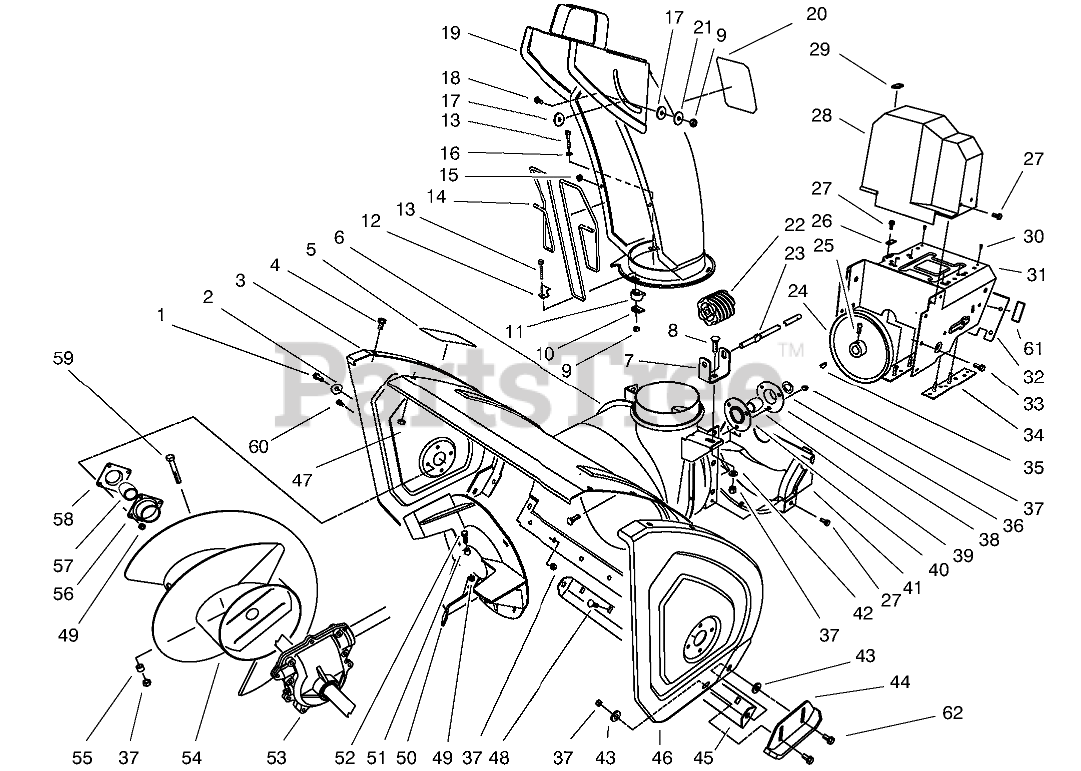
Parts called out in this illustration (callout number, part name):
1	SCREW-HH
2	WASHER
3	Plate-Side
4	SCREW-HHF
5	DECAL-WARNING, AUGER
6	Housing-28"
7	BRACKET-WORM, CHUTE
8	BOLT-CARR
9	NUT-LOCK, NI
10	PLATE-RETAINER, CHUTE
11	RETAINER-CHUTE
12	CLIP-GUARD, CHUTE
13	SCREW-HSH
14	GUARD-CHUTE
15	NUT-PUSH
16	WASHER-FLAT
17	WASHER-PLASTIC
19	Assembly
20	DECAL-DANGER (only on: 38078)
21	WASHER-FLAT
22	GEAR-WORM
23	ROD-CHUTE, LOWER
24	PULLEY-IMPELLER
25	SCREW-SET, SQH
26	RETAINER-CABLE
27	SCREW-HWH
28	COVER-BELT, UPPER
29	COVER-CABLE
30	Rivet
31	Frame-Engine
32	Cover-Frame, Engine
33	SCREW-HHF
34	CONTROL COVER
35	KEY-WOODRUFF
36	WASHER-THRUST
37	NUT-LOCK, NI
38	FLANGE-CUP, BEARING
39	BEARING-BALL
40	FLANGE-CUP, BEARING
41	COVER-BELT, LOWER
42	WASHER-PLAIN
43	WASHER
44	Skid
45	Blade-Scraper
46	Plate-Side
47	NUT-LOCK, NI
48	SCREW-CARR
49	NUT-LOCK, NI
50	Impeller
51	SPACER
52	SCREW-HHF
53	LH AUGER GEARCASE ASM
54	Auger-R.H.
55	SPACER-HUB, AUGER
56	BEARING-FLANGE, FRONT
57	BEARING
58	BEARING-FLANGE, REAR
59	SCREW-HH
60	SCREW-HH
61	DECAL
62	SCREW-HHF
